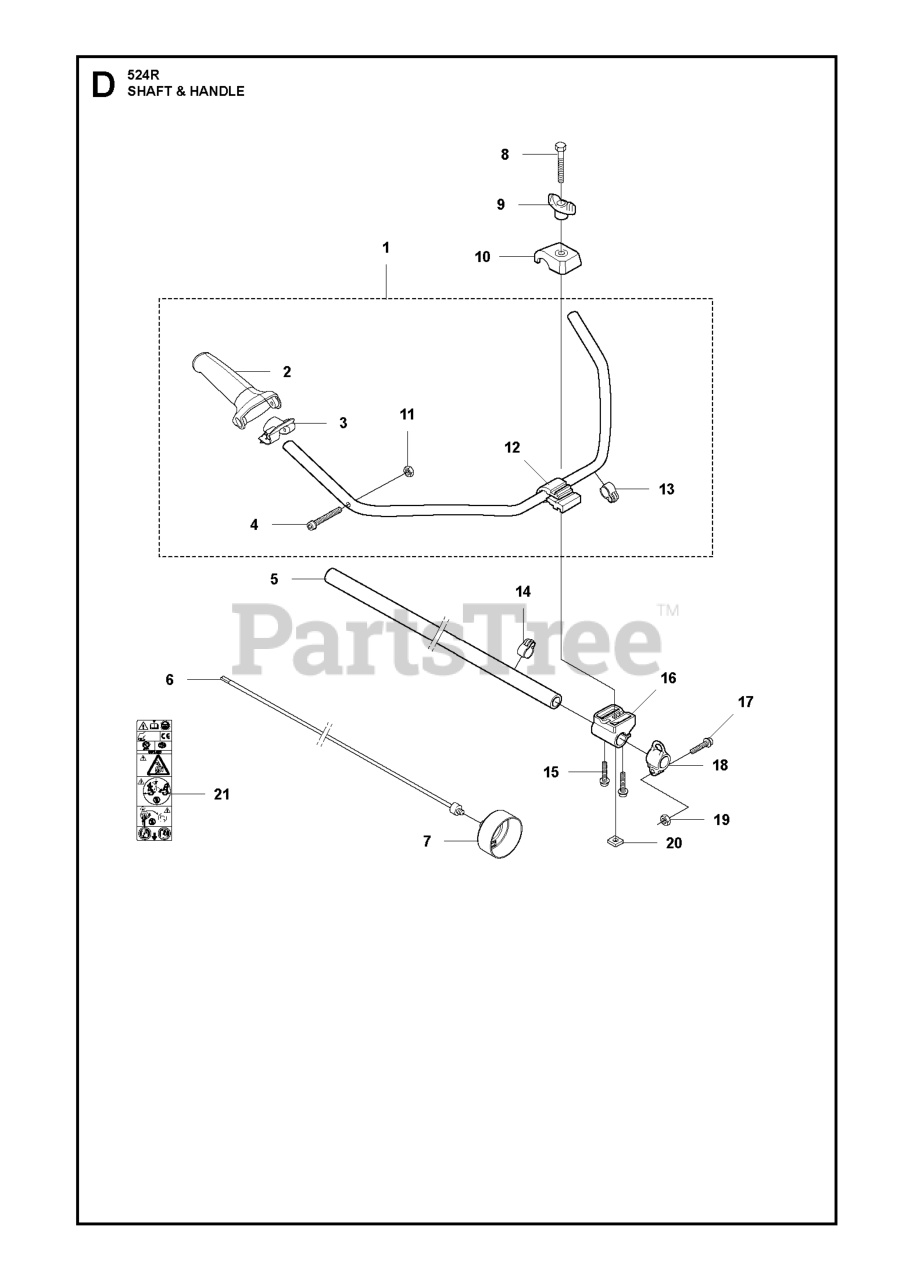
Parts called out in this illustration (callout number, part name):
5	DRIVE TUBE ASSEMBLY
6	DRIVE SHAFT
7	CLUTCH DRUM
17	SCREW
18	HARNESS HOLDER
21	LABEL WARNING TRIMMERS AND BRU
